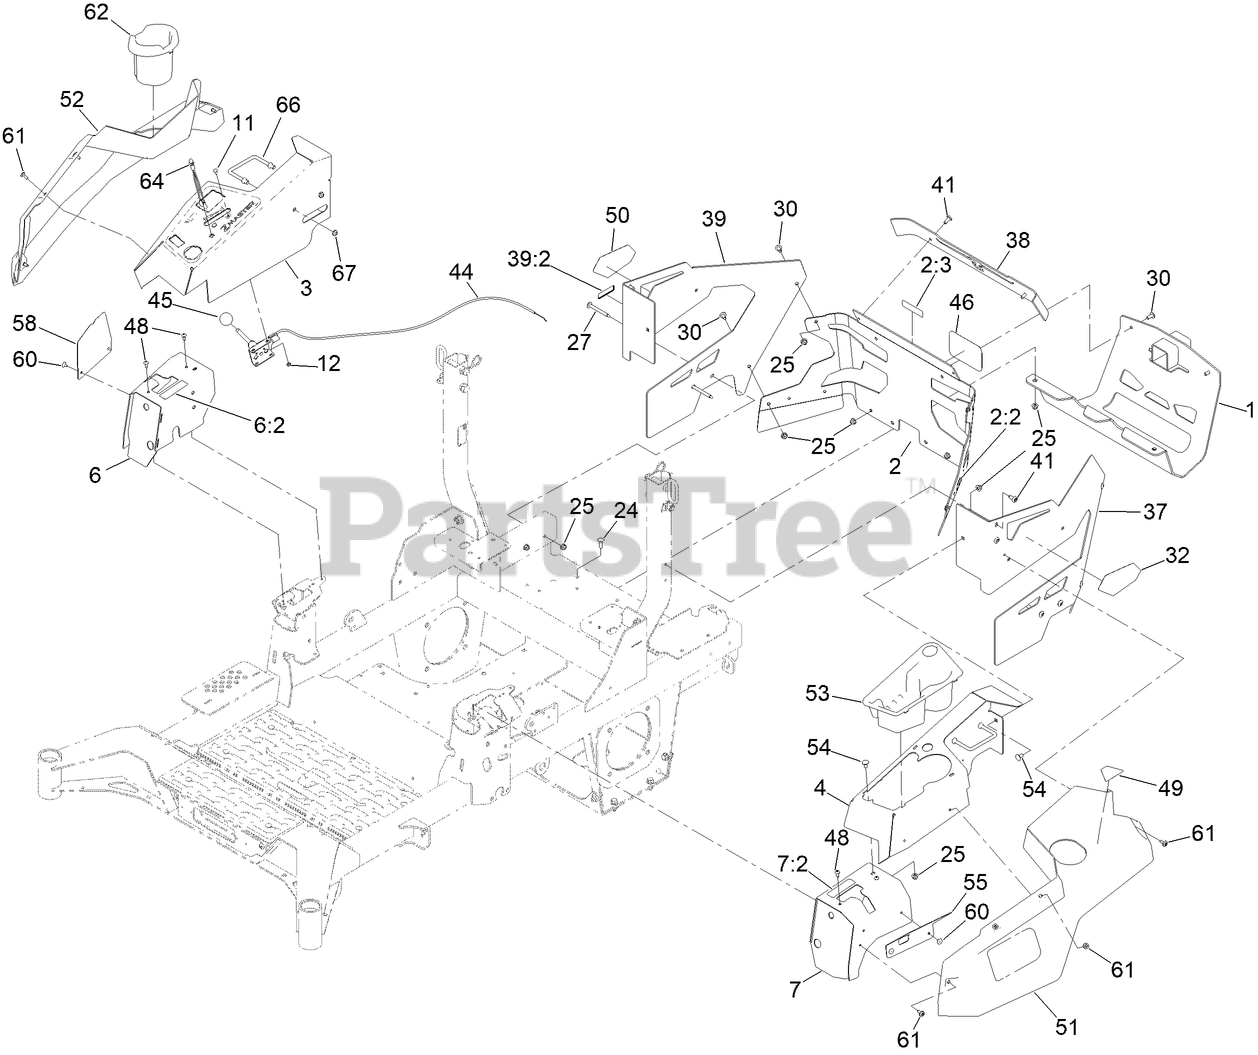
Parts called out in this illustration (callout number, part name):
1	MUFFLER GUARD ASM [BLACK]
2	REAR GUARD ASM
2:2	DECAL-WARNING
2:3	DECAL-HITCH
3	CONSOLE-RH
4	CONSOLE-LH
6	RH COVER ASM
6:2	DECAL-CONTROL, MOTION
7	LH COVER ASM
7:2	DECAL-CONTROL, MOTION
11	BOLT-CARR
12	NUT-LOCK, NI
24	SCREW-CARR
25	NUT-HF, NI
27	SCREW-TORX
30	SCREW-TORX
32	DECAL - 4000 SERIES, LH
37	GUARD-REAR, LH
38	GUARD-REAR, TOP
39	RH REAR GUARD ASM
39:2	DECAL-ARRESTOR, SPARK
44	CABLE-CONTROL, THROTTLE
45	KNOB-BALL
48	SCREW-TPH THD FORM
49	DECAL-FILL, FUEL
50	DECAL-4000 SERIES, RH
51	SIDE POD, LH
52	SIDE POD, RH
53	CUP HOLDER
54	SCREW-CARR
55	PLATE-COVER, LH FRONT
58	PLATE-COVER, RH FRONT
60	RIVET-TRIFOLD
61	SCREW-SHOULDER
62	CUPHOLDER-RH
64	INDICATOR-LED, RED
66	ROD-SUPPORT, POD
